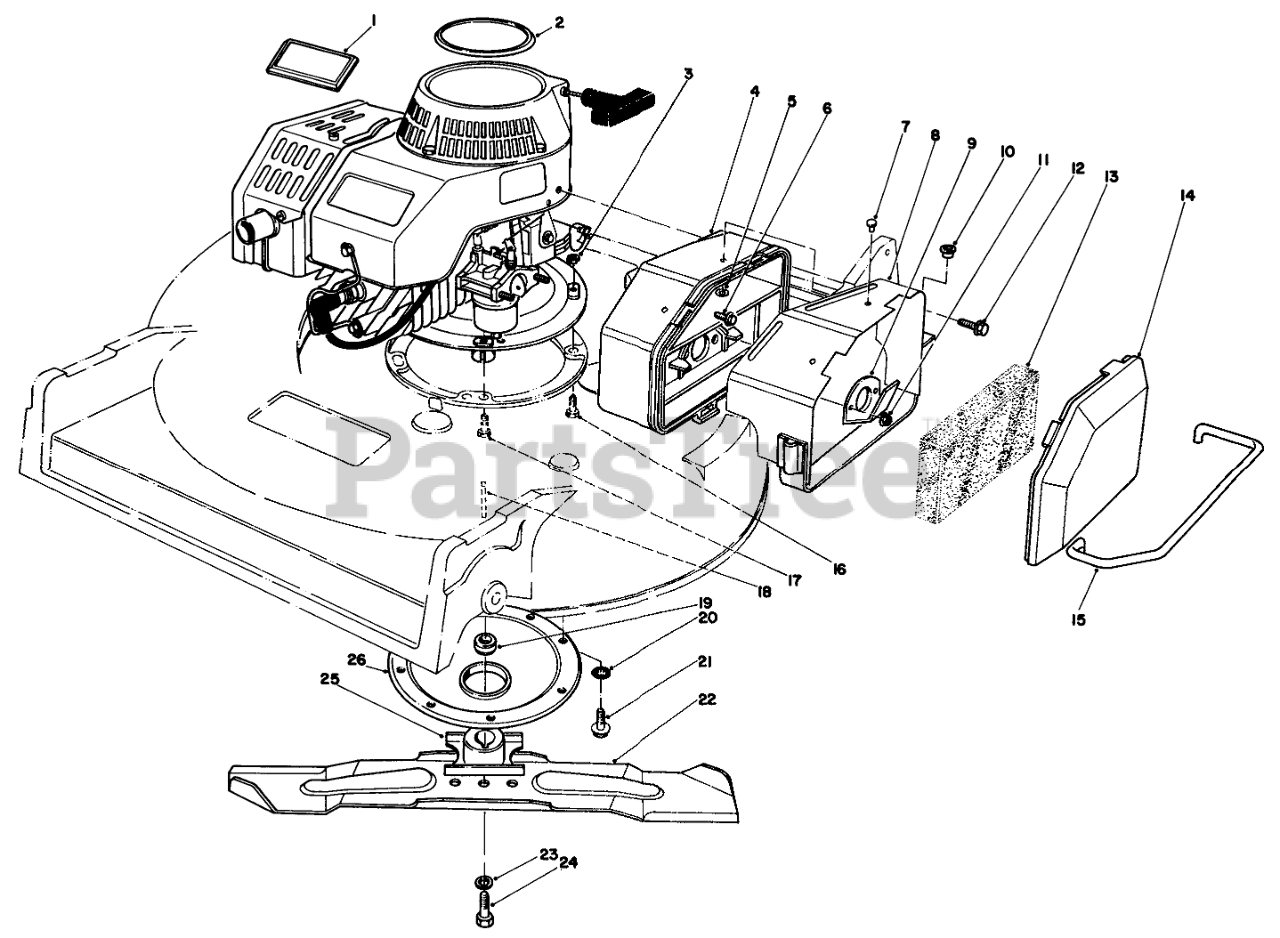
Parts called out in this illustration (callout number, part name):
1	Plate-Logo
2	Plate-Engine Logo
3	NUT-JAM
4	Air Cleaner Assembly (Incl. Ref. #5, 7, 8)
5	WASHER-FLAT
6	HEX FL HD M.6X1.0X25MM
7	RIVET-POP
8	AIR CLEANER COVER WA
9	SPIT BACK DEFLECTOR
10	5/16 ID BSHG
11	NUT-LOCK
12	SCREW-HHF
13	FILTER
14	AIR CLEANER COVER
15	AIR CLEANER GUARD
16	SCREW-HH
17	SCREW-HH
18	KEY-SQUARE
19	SPACER-BLADE RETAINER
20	WASHER-LOCK, INTERNAL
21	SCREW-HWHTF
22	BLADE-21in
23	WASHER-LOCK
24	SCREW-BLADE
25	RETAINER-BLADE
26	PROTECTOR-CRANKSHAFT
